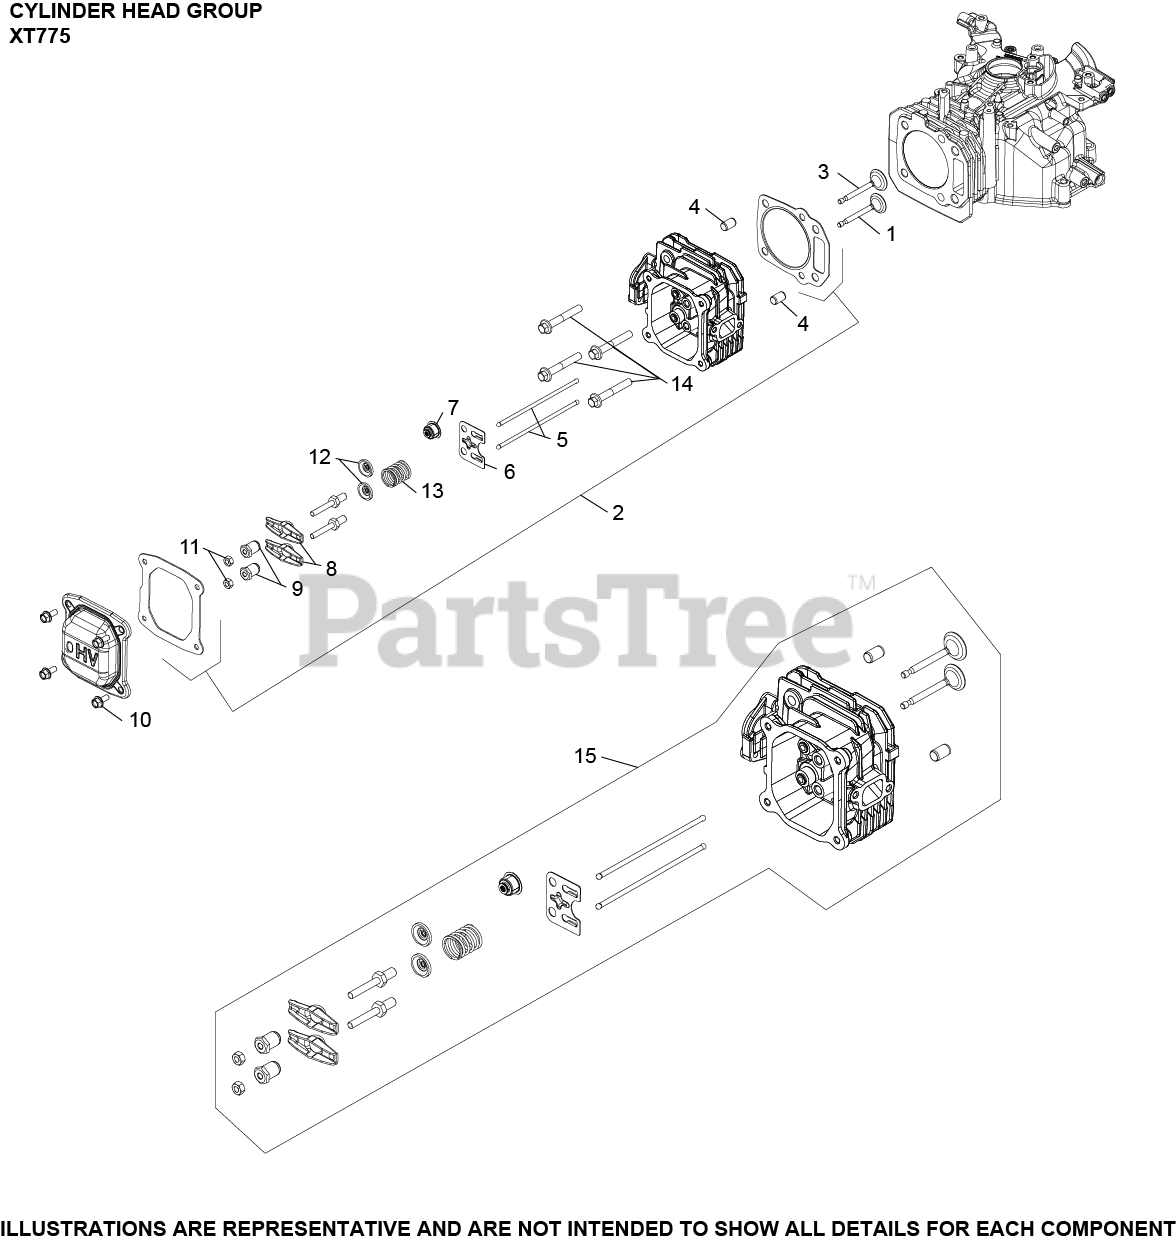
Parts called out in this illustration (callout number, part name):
1	VALVE, EXHAUST
2	KIT, HEAD GASKET
3	VALVE, INTAKE
4	DOWEL, CYLINDER HEAD
5	ROD, PUSH
6	PLATE, PUSHROD GUIDE
7	SEAL, VALVE STEM
8	ARM, ROCKER
9	PIVOT, ROCKER ARM
10	SCREW, HEX FLANGE (M6) (CKY)
11	NUT, HEX JAM
12	RETAINER, VALVE SPRING
13	SPRING, VALVE
14	SCREW, HEX FLANGE M8
15	KIT, VALVE TRAIN
